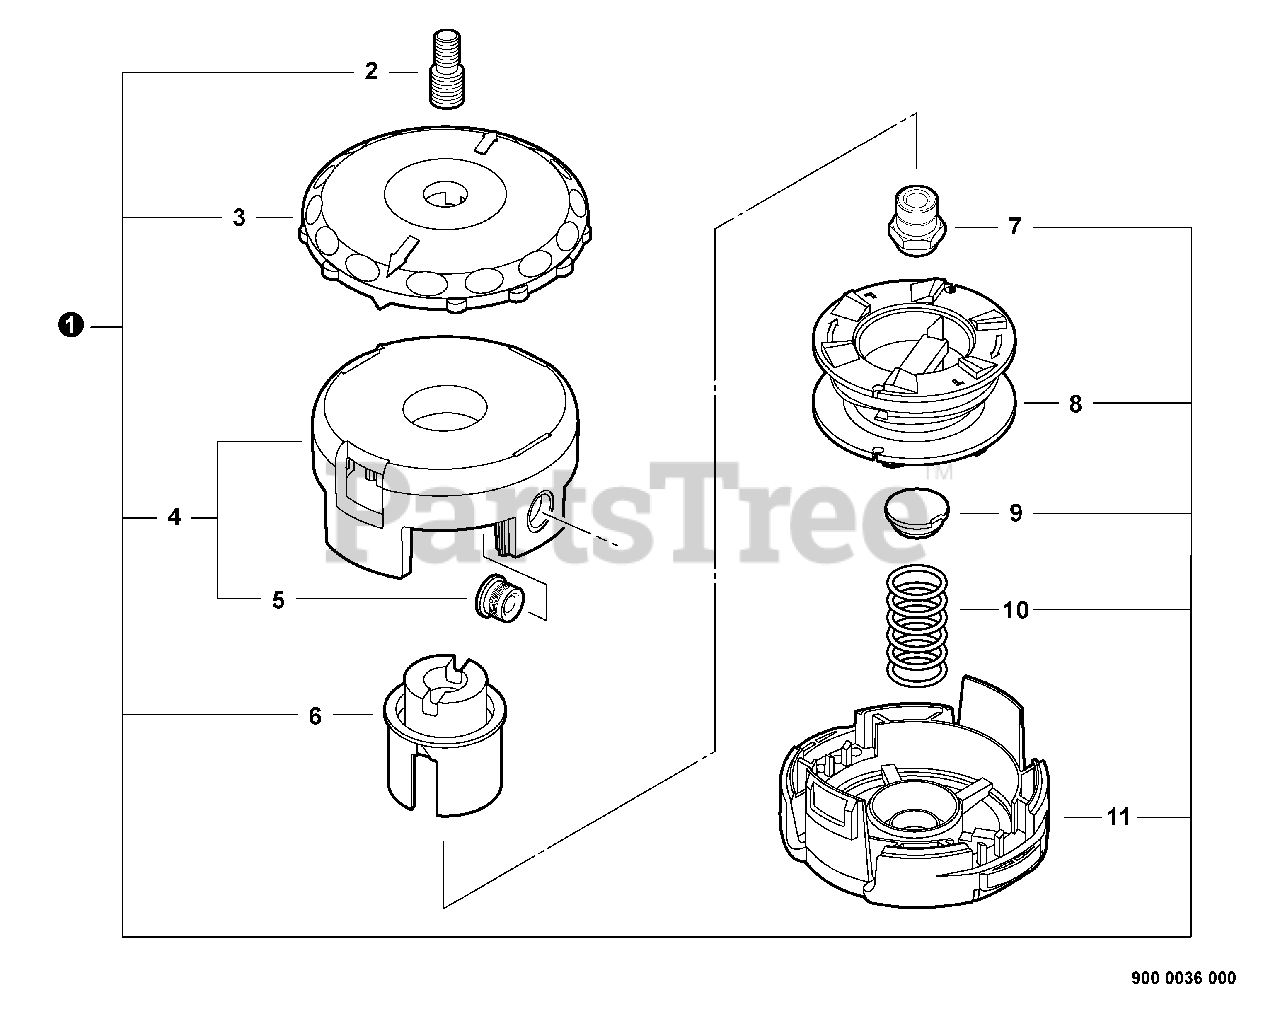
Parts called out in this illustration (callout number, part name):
1	SPEED-FEED 400 TRIMMER HEAD
2	STUD - BLACK -- RIGHT HAND
4	SPOOL COVER ASSY
6	HUB - WHITE -- RIGHT HAND
7	ARBOR - BLACK -- RIGHT HAND
9	RETAINER, SPRING
